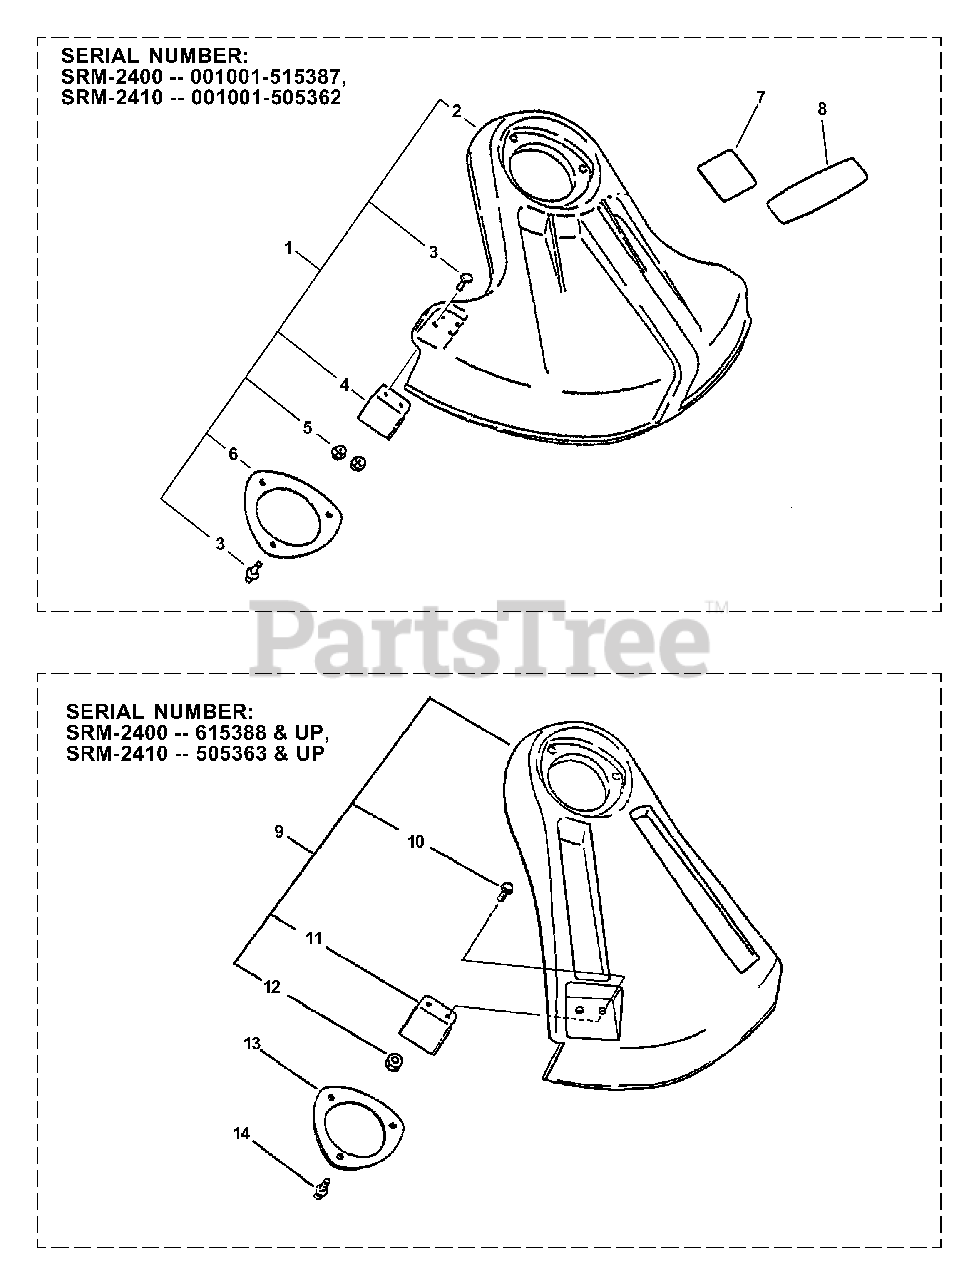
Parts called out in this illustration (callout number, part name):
1	DEBRIS SHIELD KIT
2	SHIELD, DEBRIS - PLASTIC
3	SCREW - 5X16
4	KNIFE, TRIMMER LINE
5	NUT - 5
6	PLATE, SHIELD
7	LABEL - CAUTION
8	LABEL - ECHO
9	DEBRIS SHIELD KIT - PLASTIC
10	SCREW - 5X16
11	KNIFE, TRIMMER LINE
12	NUT - 5
13	PLATE, SHIELD
14	SCREW - 5X16
